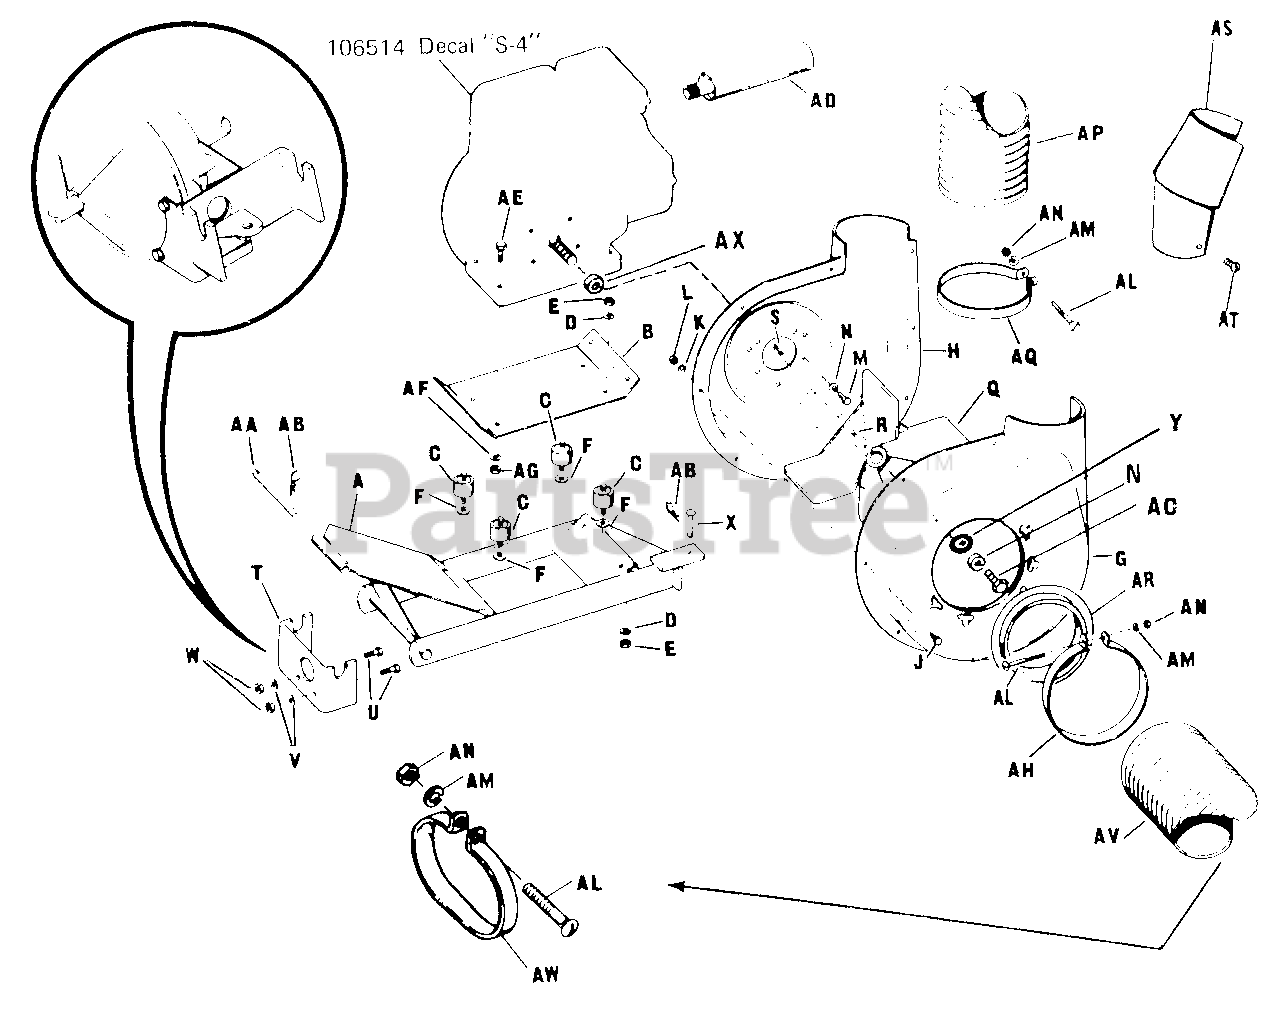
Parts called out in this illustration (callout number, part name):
A	Frame Assembly
B	Engine Plate
C	Connector, Cushion
D	Lock Washer 5/16
E	Full Hex Nut 5/16"-18NC
F	Plain Washer 5/16
G	Housing, Inlet Half
H	Housing Half-Blower, R.H.
J	Hex Cap Screw 1/4"-20NC x 1/2"
K	Lock Washer 1/4"
L	Full Hex Nut 1/4"-20NC
M	Hex Cap Screw 5/16"-24 NF x 5/8"
N	Lock Washer 5/16
Q	Fan Assembly
R	Set Screw 5/16-18 x 1/2"
S	Key
U	Hex Cap Screw 3/8"-16 x 1-1/2"
V	Lock Washer 3/8
W	Full Hex Nut 3/8"-16NC
X	Pin
AA	Counterweight Pin
AB	Spring Clip
AC	Hex Capscrew, 5/16-24 x 3/4"
AE	Hex Capscrew 5/16"-18 x 1-1/2"
AF	Lock Washer 5/16"
AG	Full Hex Nut 5/16"-18NC
AH	Hose Clamp
AL	Hd. Rd. Mach. Screw 1/4"-20 x 3"
AM	Lock Washer 1/4"
AN	Full Hex Nut 1/4"-20NC
AP	Exhaust Hose 6" Diameter
AQ	Hose Clamp
AR	Flange-Hose
AS	Deflector
AT	Self-Tapping Screw No. 10 x 3/8" lg.
AV	Intake Hose 7" Diameter
AW	Hose Clamp
